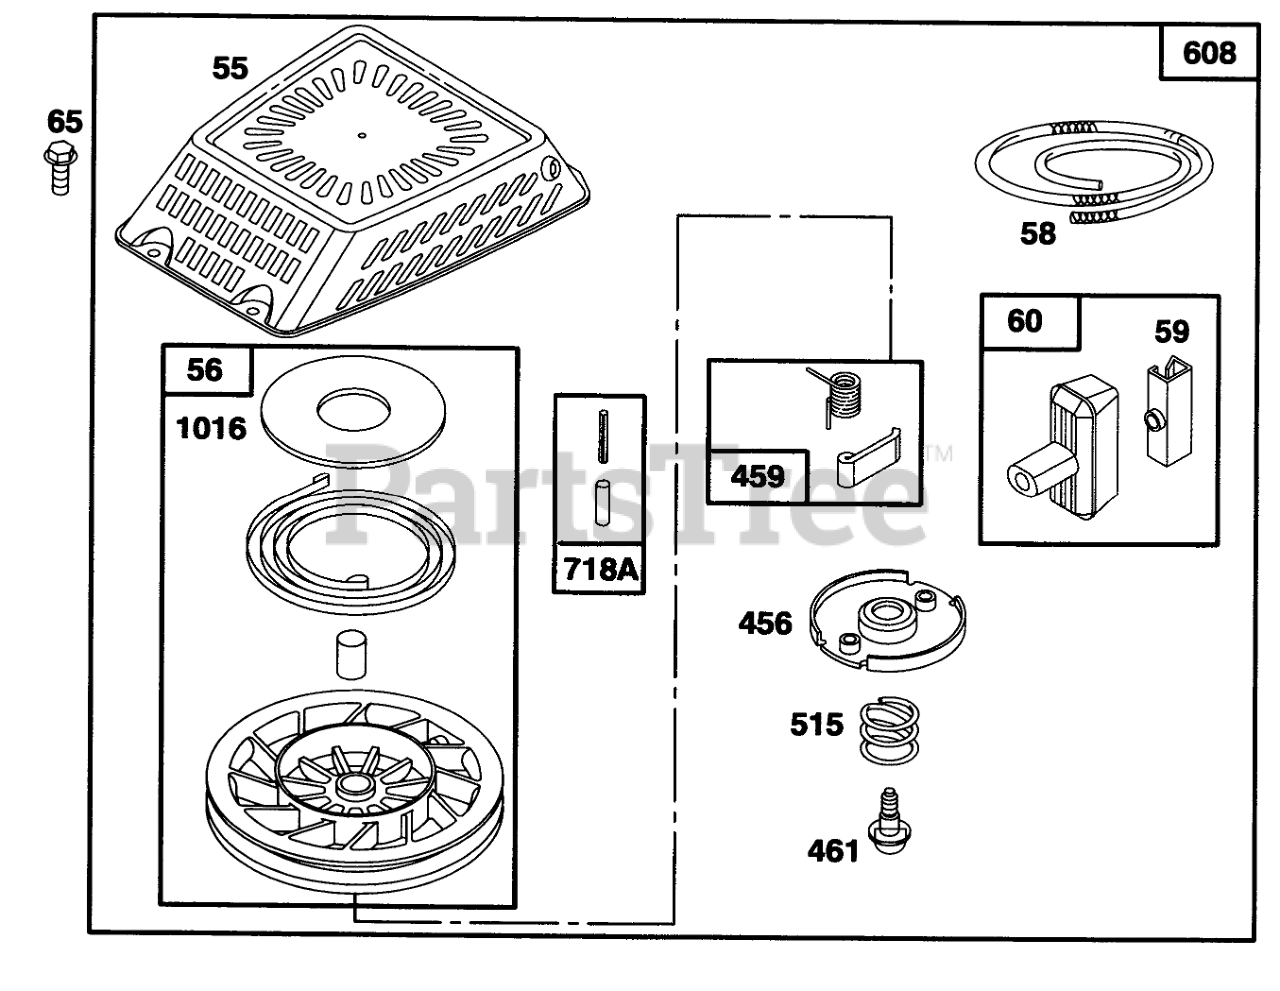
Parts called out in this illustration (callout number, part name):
55	Housing Rewind Starter
56	REWIND STARTER PULLEY
58	ROPE - STARTER
59	INSERT-HANDLE, REWIND
60	HANDLE-STARTER, REWIND
65	SCREW - HEX HEAD
456	RETAINER - SPRING
459	PAWL - RATCHET
461	SCREW - HEX HEAD
515	0 Spring-Torsion
608	StarterAssy-Rewind
718A	DAWL - SLEEVE
1016	COVER - PULLEY
